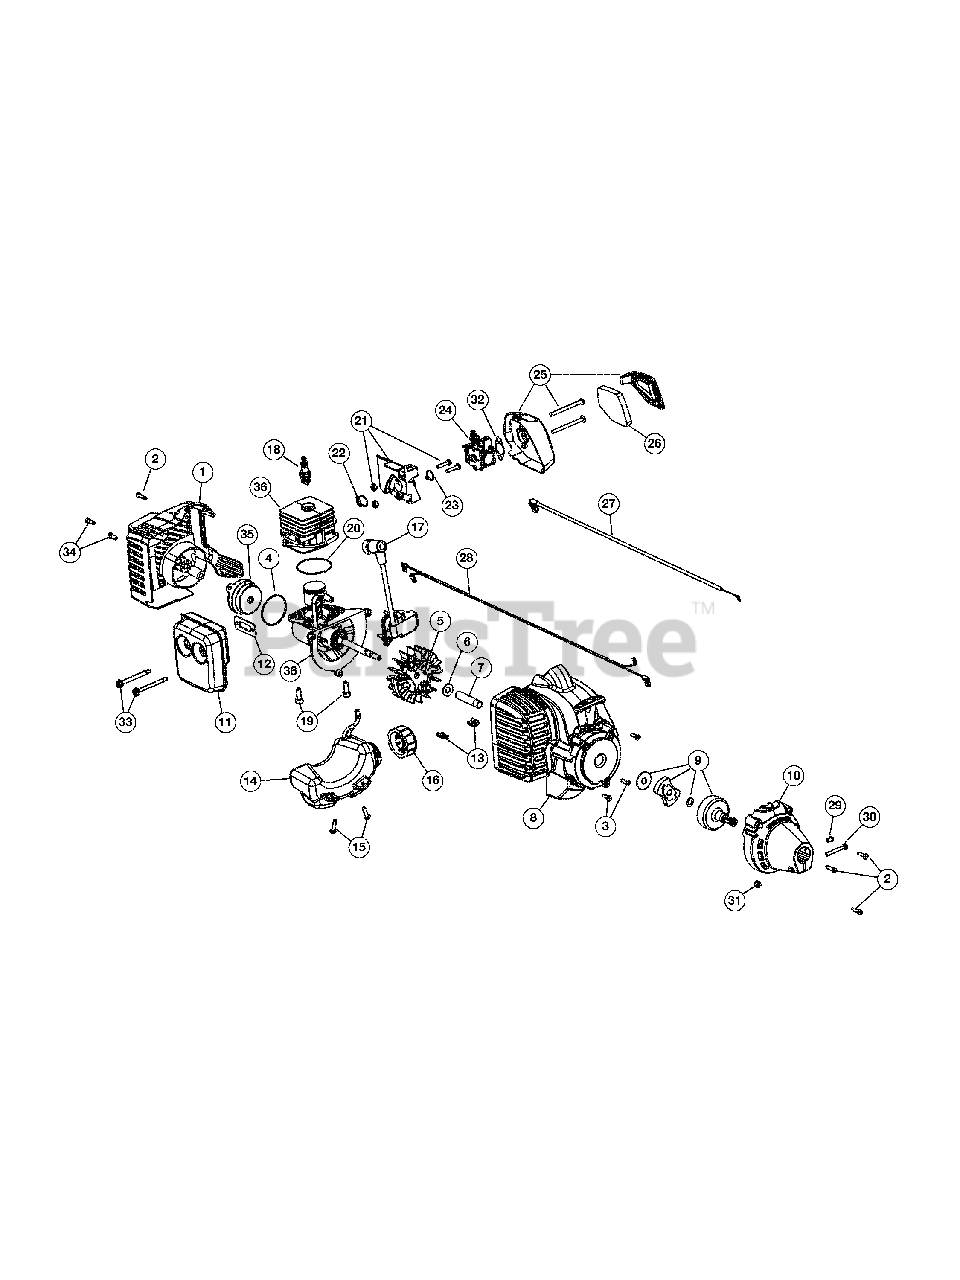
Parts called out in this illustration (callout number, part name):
1	Rear Cover Assembly (includes 2 & 34)
2	Cover Screw
3	Housing Screw
4	O-Ring
5	Flywheel Assembly
6	Washer
7	Spacer
8	Starter Housing (includes 3 & 13)
9	Clutch Assembly
10	Clutch Cover (includes 2)
11	Muffler Assembly (includes 12 & 33)
12	Muffler Gasket
13	U-shaped Nut
14	Fuel Tank Assembly (includes 15 & 16)
15	Tank Screw
16	Fuel Cap
17	Module Assembly
18	Spark Plug
19	Crankcase Bolt
20	Crankcase O-Ring
21	Insulator Assembly (includes 22 & 23)
22	Insulator O-Ring
23	Carburetor O-Ring
24	Carburetor
25	Aircleaner Cover Assembly (includes 26)
26	Aircleaner Filter
27	Throttle Cable
28	Lead Wires
29	Anti-rotation Screw
30	Clamp Screw
31	Clamp Nut
32	Air Cleaner Gasket
33	Muffler Screw
34	Rear Housing Screw
35	Electric Starter Cover Assembly
36	Short Block Assembly (includes 4-7 & 17-20)
